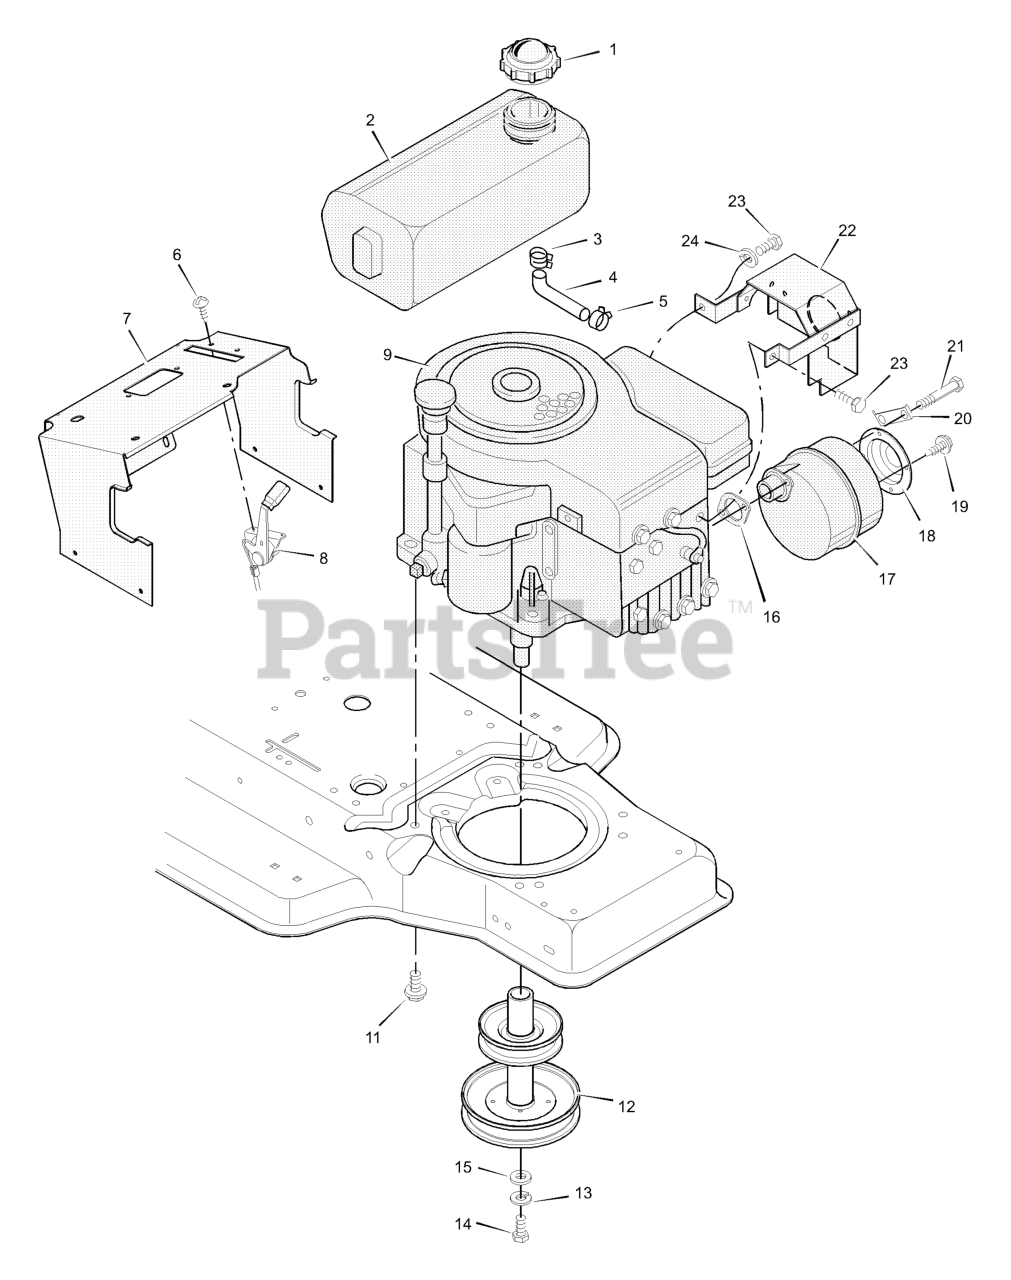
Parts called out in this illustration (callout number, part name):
1	Fuel Cap
2	Fuel Tank
3	Hose Clamp
4	Fuel Line
5	Hose Clamp
7	Support, Dash
8	Throttle Control
9	Engine *
11	Bolt, Engine Mount
12	Stack Pulley Assembly
13	Lockwasher
14	Bolt, Hex
16	GASKET, Exhaust
17	Muffler
18	Deflector, Muffler
20	Lock, Screw
22	Shield, Heat
23	Bolt
